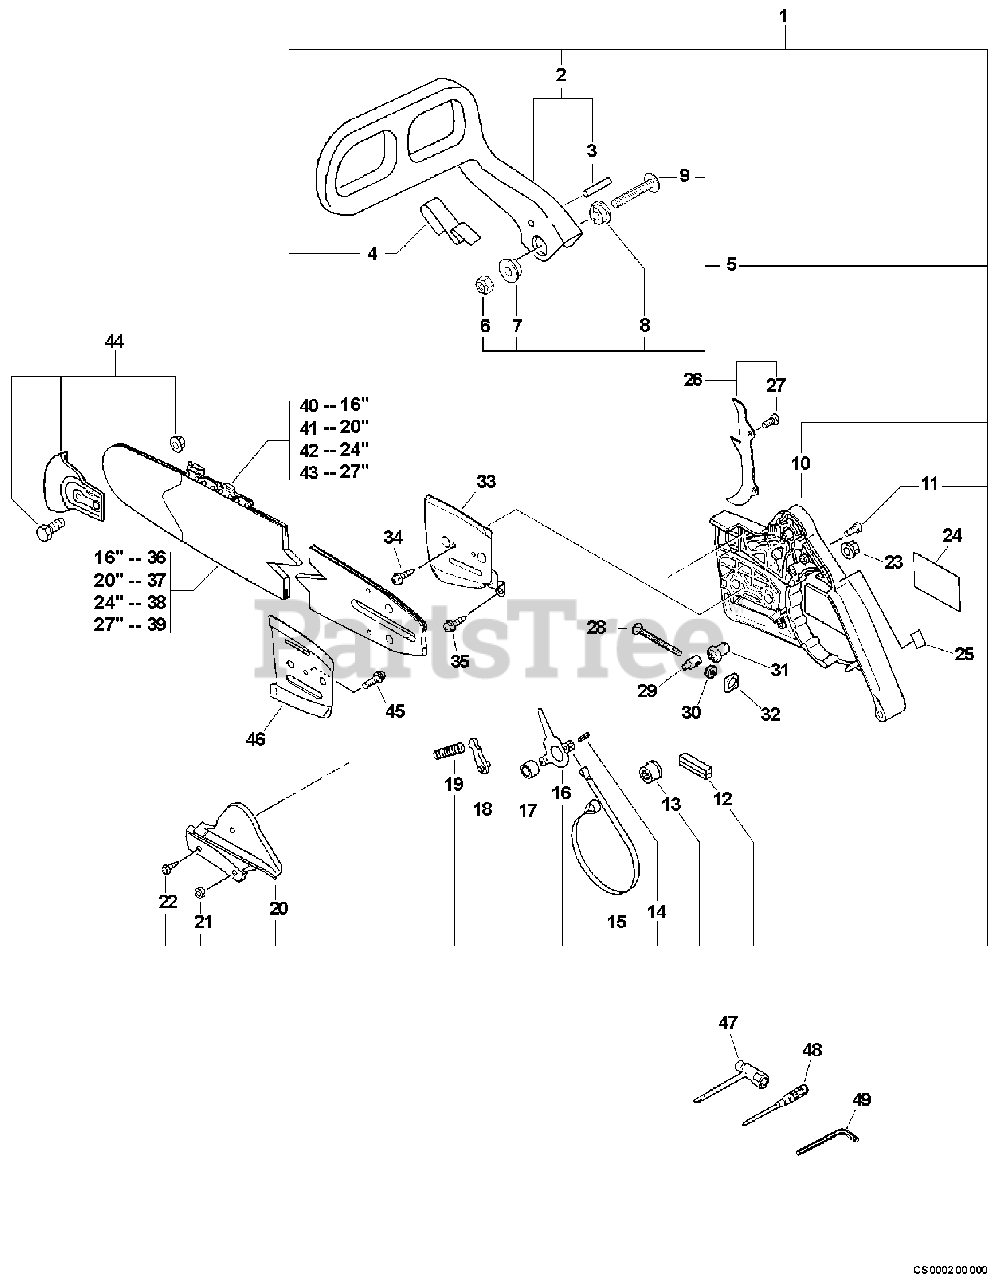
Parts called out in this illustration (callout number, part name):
1	CHAIN BRAKE ASSY
2	LEVER, BRAKE
3	PIN 3.5×26
4	SPRING, FLAT
5	SCREW KIT
6	NUT, LOCK M5
7	COLLAR 5.3×10×13×L5
8	COLLAR 5
9	SCREW 5×35
10	GUARD, SPROCKET
11	SCREW 3×18
12	SEAL, BRAKE
13	ADJUSTER, BRAKE
14	PIN, SPRING 4×8.8
15	BAND, BRAKE
16	LEVER, BRAKE
17	SPACER 8×12×9
18	STOPPER, BRAKE
19	SPRING, BRAKE
20	COVER, BRAKE
21	NUT 3 MM
22	SCREW 4×12
23	NUT, FLANGE M8×1.25
24	LABEL - ECHO
25	LABEL, OILER
26	SPIKE KIT, BUMPER
27	BOLT 5×12
29	TENSIONER, CHAIN
30	GEAR, BEVEL
31	GEAR, BEVEL
32	COLLAR 8
33	PLATE, GUIDE - OUTER
34	SCREW 3×6
35	SCREW 4×10
36	GUIDE BAR, 16" POWER MATCH
37	GUIDE BAR, 20" POWER MATCH
38	GUIDE BAR, 24" POWER MATCH
39	GUIDE BAR, 27" POWER MATCH
40	SAWING CHAIN - 16" -- VANGUARD
41	SAWING CHAIN - 20" -- VANGUARD
42	SAWING CHAIN - 24" -- VANGUARD
43	CHAIN
44	KICK GUARD KIT
45	SCREW 4×8
46	PLATE, GUIDE - INNER
47	T-WRENCH 13×19×180
48	SCREWDRIVER, PHILLIPS
49	WRENCH, ALLEN 4 MM
